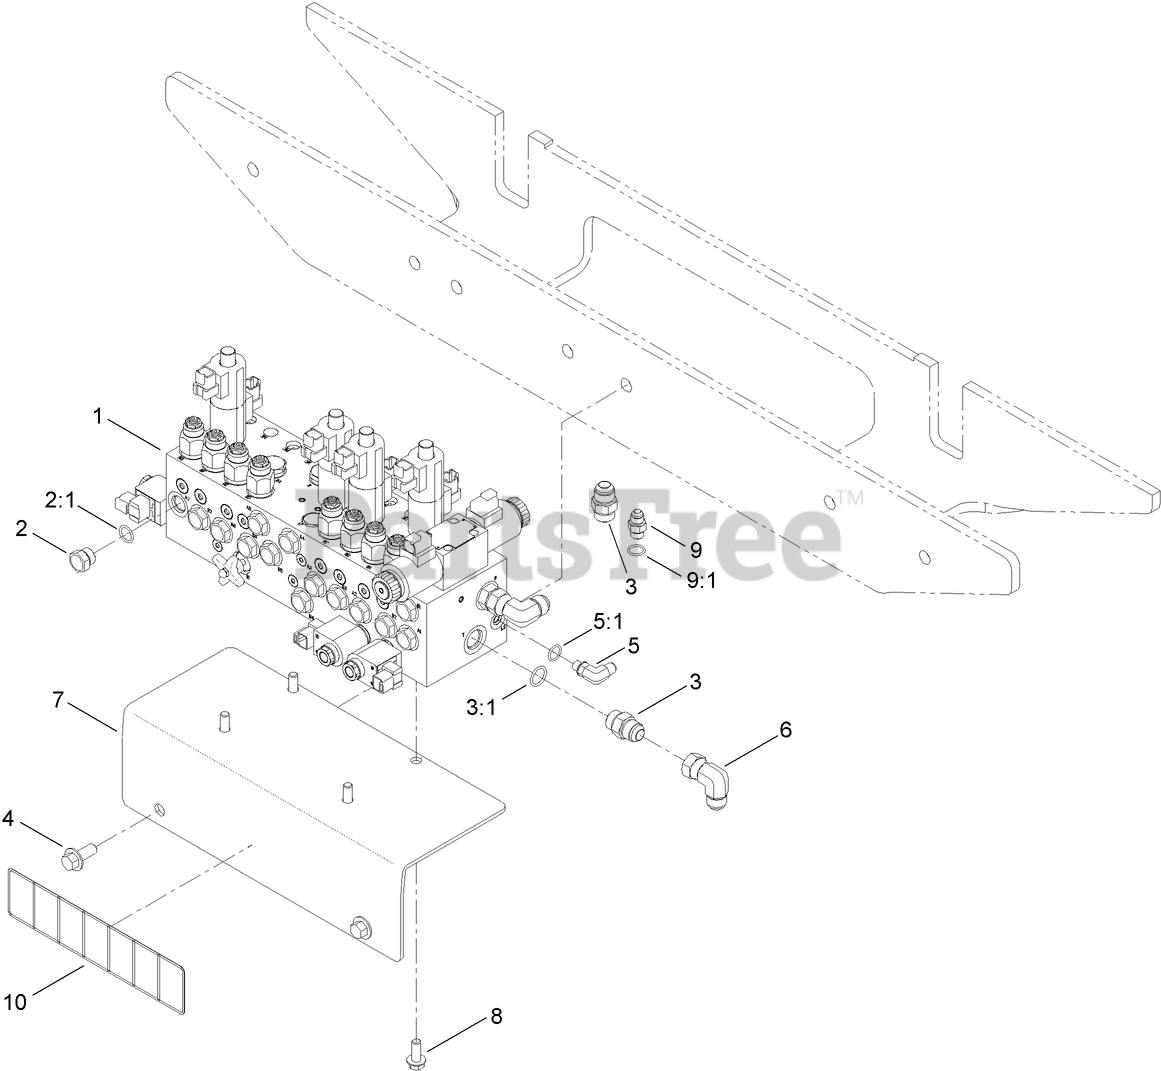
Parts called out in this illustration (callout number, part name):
1	HYD AUXILLARY MANIFOLD ASM
2	PLUG-HEX HD
2:1	O-RING
3	FITTING-STRAIGHT
3:1	O-RING
4	SCREW-HHF
5	ELBOW-90, ADJ
5:1	O-RING
6	ADAPTOR
7	BRACKET-MOUNT, VALVE
8	SCREW-HHF
9	FITTING-STRAIGHT
9:1	O-RING
10	DECAL-LEGEND, CONTROL VALVE
